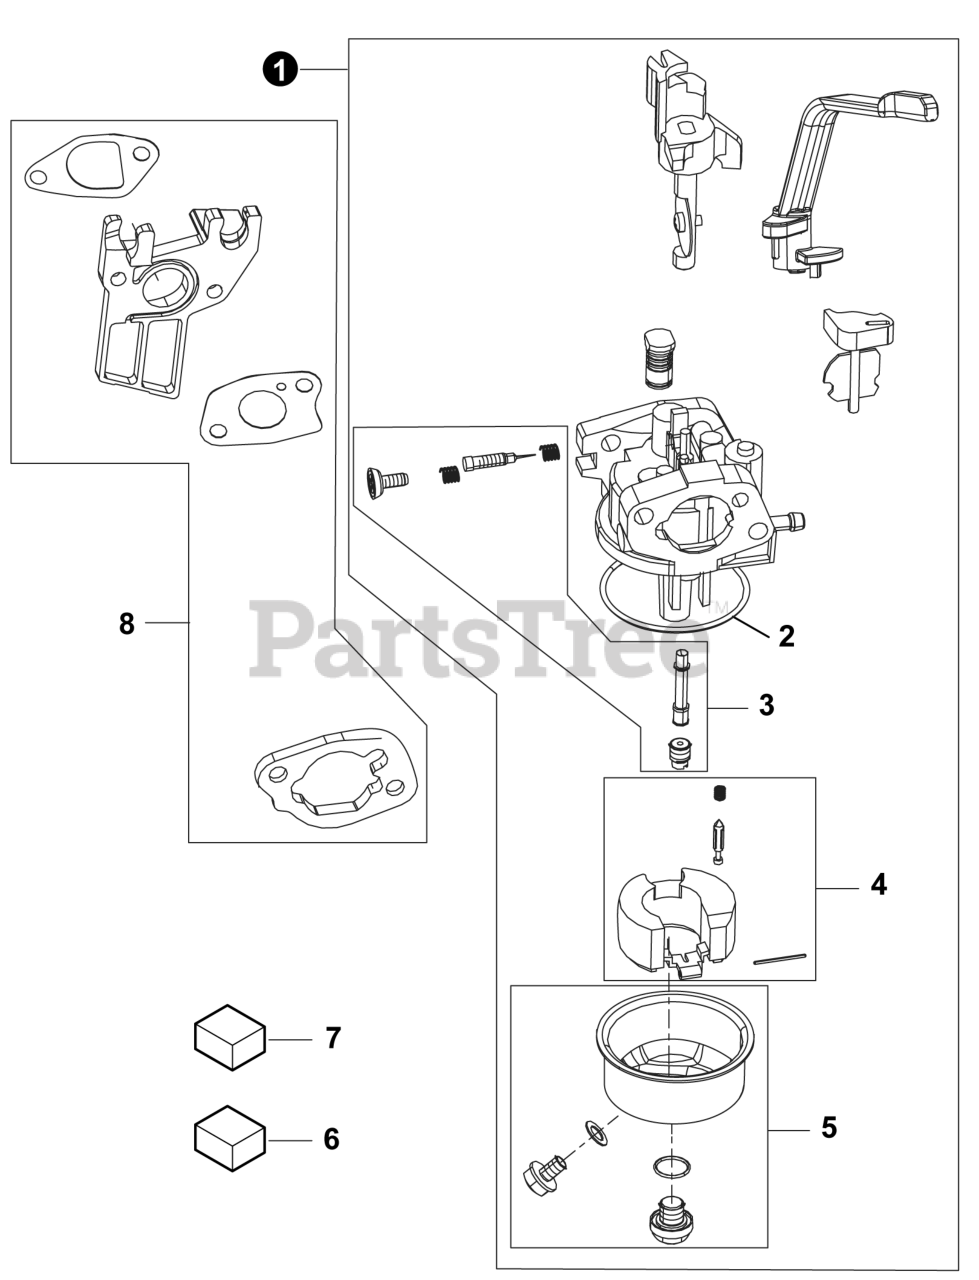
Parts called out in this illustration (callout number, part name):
1	CARBURETOR ASSY.
2	GASKET, CARB BOWL
3	KIT, MAIN JET
4	KIT, FLOAT
5	KIT, BOWL
6	KIT, EG-3500 HIGH ALTITUDE JET 3-6K
7	KIT, EG-3500 HIGH ALTITUDE JET 6-8K
8	GASKET SET, INTAKE
